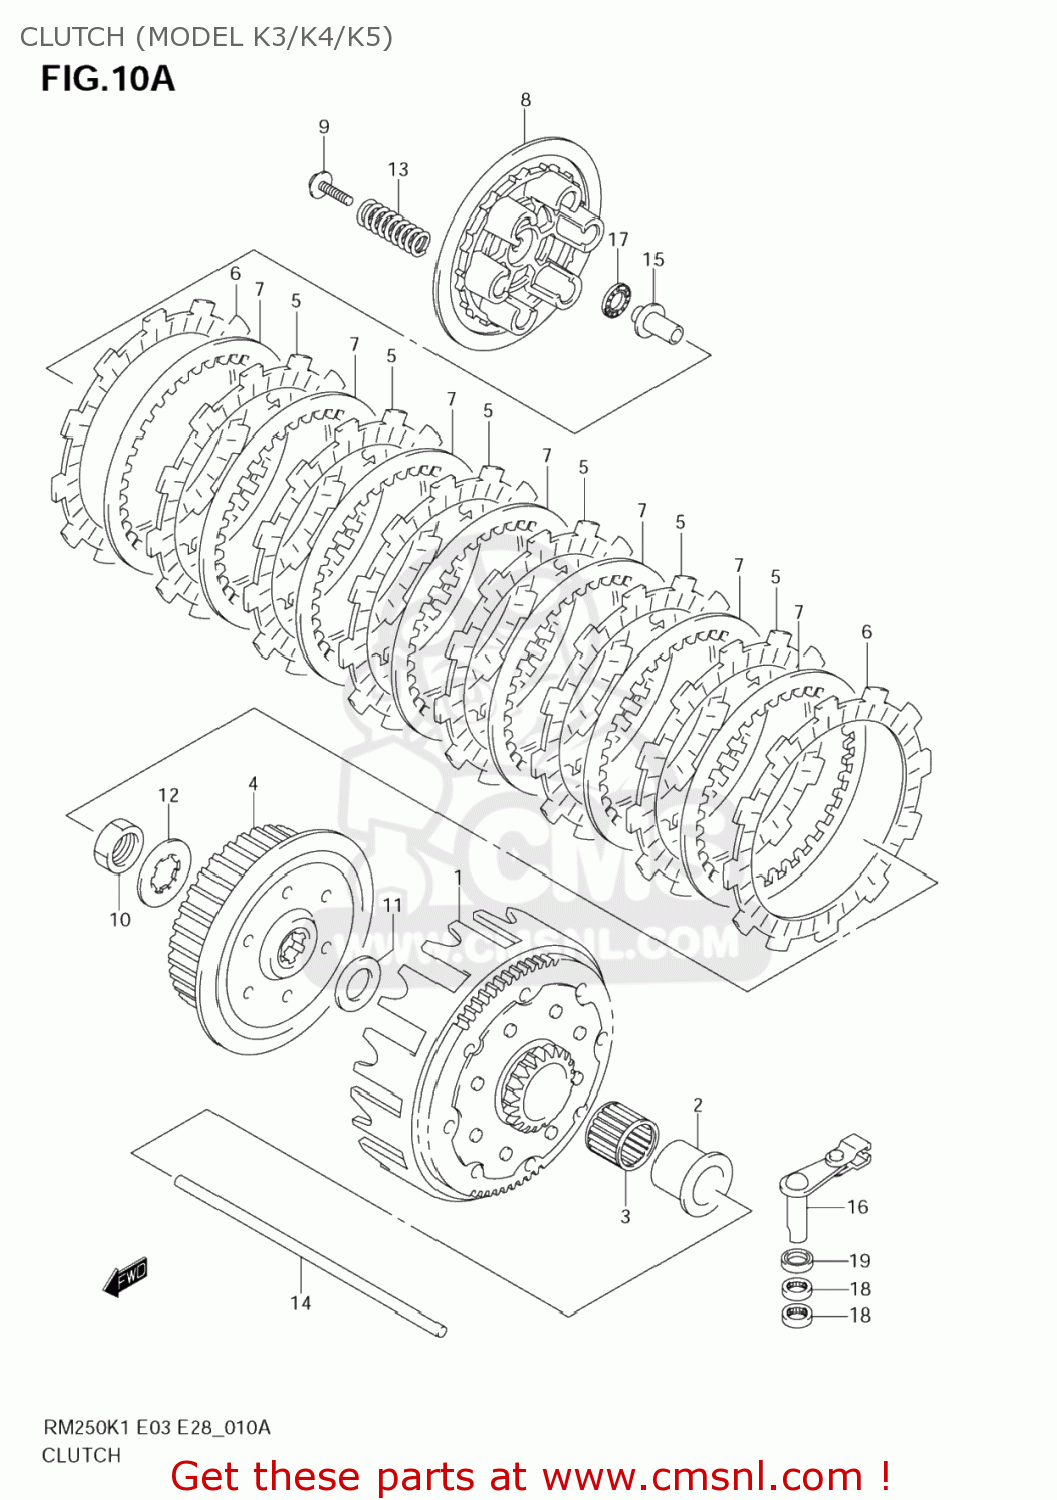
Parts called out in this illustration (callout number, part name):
1	GEAR ASSY,PRIM
2	SPACER,PRIMARY DRIVEN
3	BEARING(29X34X27)
4	HUB,CLUTCH SLEEVE
5	PLATE,CLUTCH DRIVE NO.1 (NAS)
6	PLATE,CLUTCH DRIVE NO.2 (NAS)
7	PLATE,CLUTCH DRIVEN (NAS)
8	DISC,CLUTCH PRESSURE
9	BOLT(5X25)
10	NUT
11	WASHER(22X38X2)
12	WASHER,LOCK
13	SPRING
14	ROD,CLUTCH PUSH
15	PIECE,CLUTCH PUSH
16	CAMSHAFT,CLUTCH RELEASE
17	BEARING(10X22X2.8)
18	BEARING(12X16X10)
19	SEAL,OIL(12X19X5)
